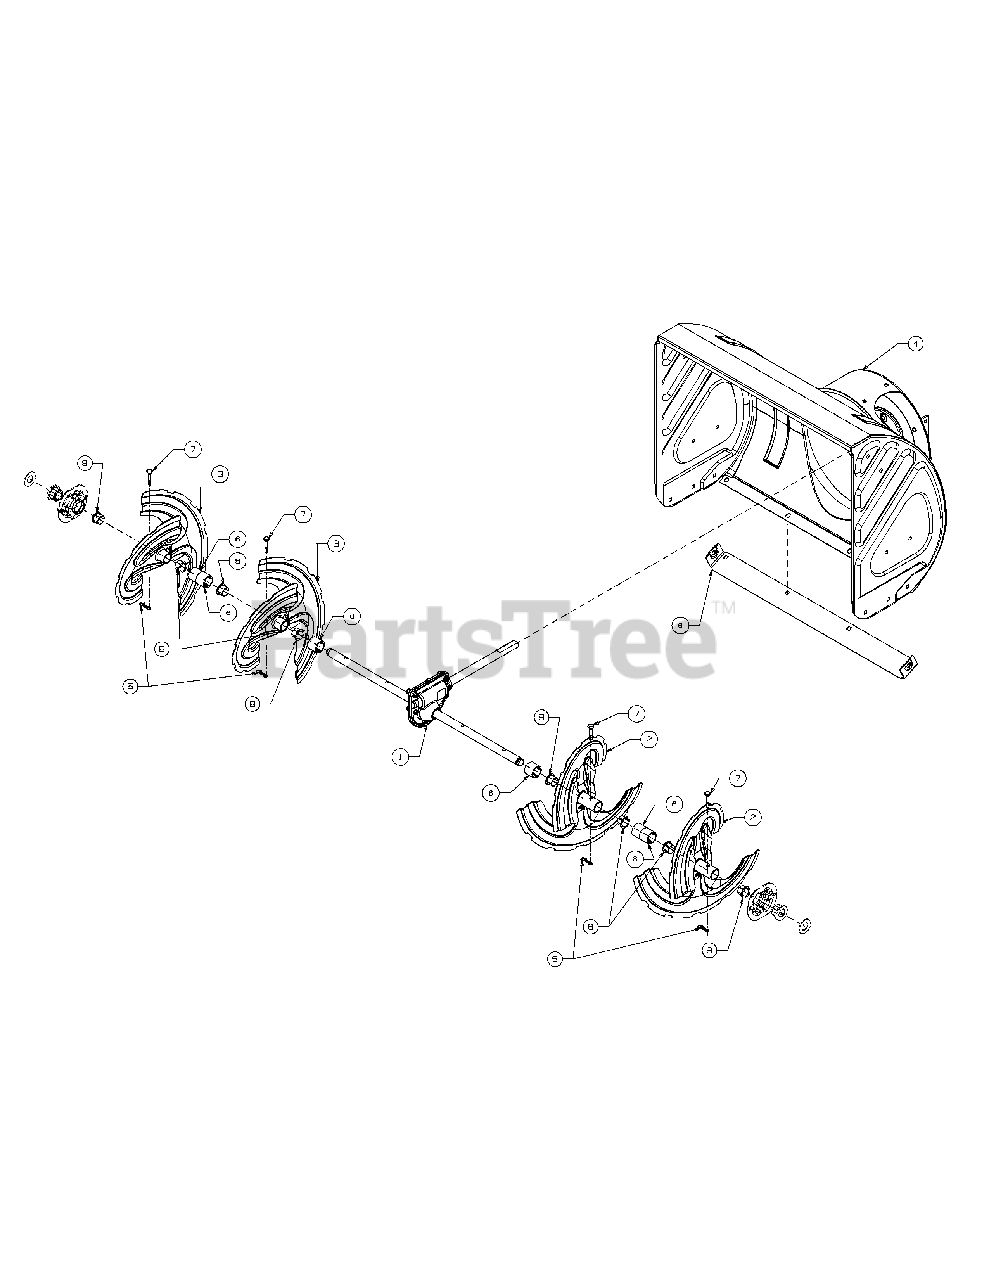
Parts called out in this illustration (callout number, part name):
1	Gearbox Asm-Auger 26"
2	Auger Assembly-LH
3	Auger Assembly-RH
4	Housing Assy-Auger
5	Pin-Cotter
6	Spacer 1.25Od X
7	Pin-Shear .25
8	Flange Bearing
9	Plate-Shave 26"
